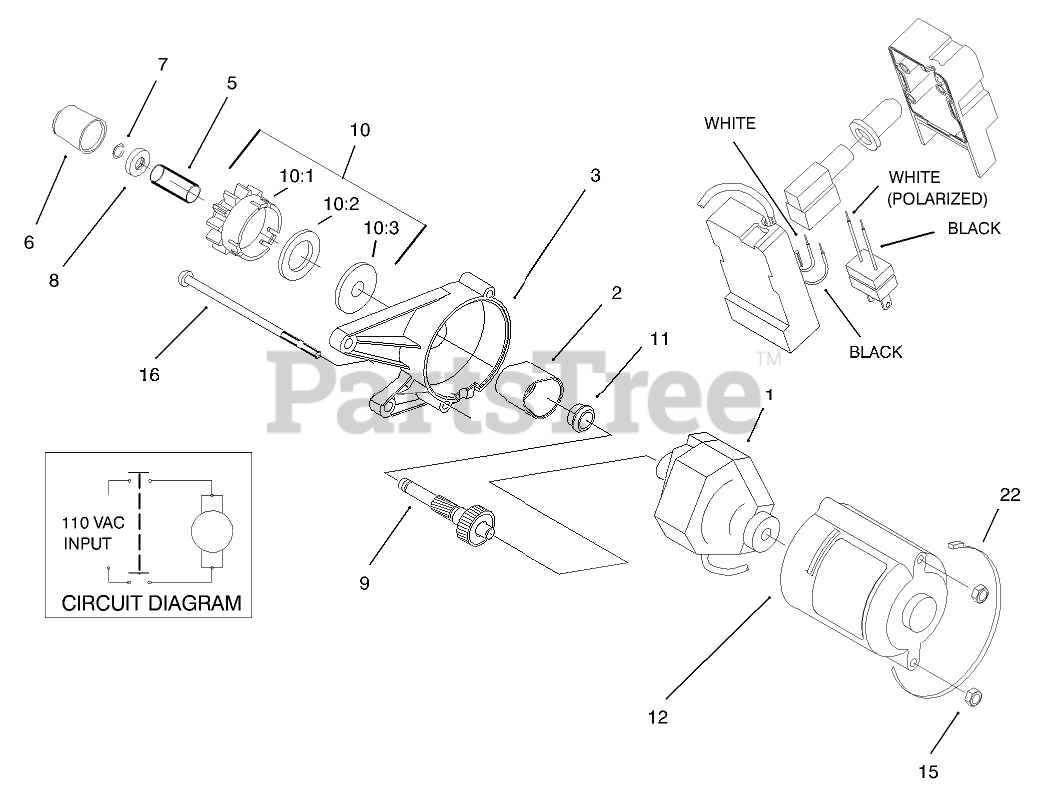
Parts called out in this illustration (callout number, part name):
1	Starter Motor Assembly (only on:38182)
2	Cover-Gear (only on:38182)
3	Housing-UpperStarter (only on:38182)
5	Spring (only on:38182)
6	Pinion-Cap (only on:38182)
7	Ring-Lock (only on:38182)
8	Stop-Pinion (only on:38182)
9	Shaft/Gear Ay X(only on: 38182)
10	Pinion ASM (R & S)(only on: 38182)
10:1	Nut (only on: 38182)
10:2	Pinion (only on:38182)
10:3	Ring-Rubber (onlyon: 38182)
11	Bushing (only on:38182)
12	Housing-LowerStarter (only on:38182)
15	Nut-Lock (only on:38182)
16	Screw-Mach (onlyon: 38182)
22	Tie-Cable (only on:38182)
